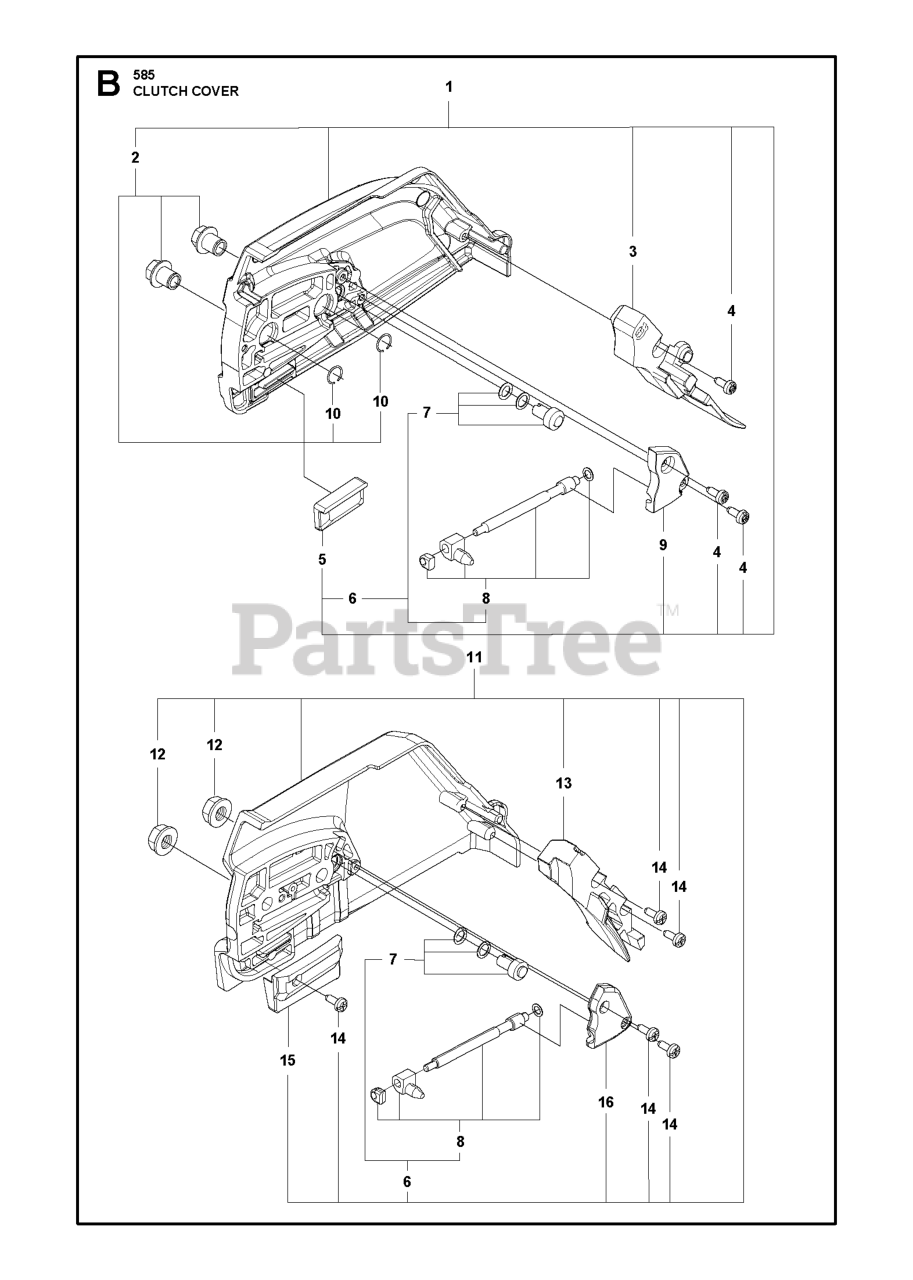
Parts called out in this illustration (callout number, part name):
1	CLUTCH COVER ASSY STANDARD REW
2	CHAIN BRAKE KIT UNLOSABLE NUTS
3	CHIP GUARD
5	CHAIN GUIDE
6	CHAIN TENSIONER KIT H565/H572
7	WORM WHEEL KIT H565/H572
8	WORM SCREW KIT H565/H572
9	COVER WORM SCREW
10	SNAP RING SNAP RING 12X10X1
11	Covers
12	NUT M8 FLANGE
13	PROTECTOR
14	SCREW CITXPANT
15	CHAIN GUIDE
16	COVER
